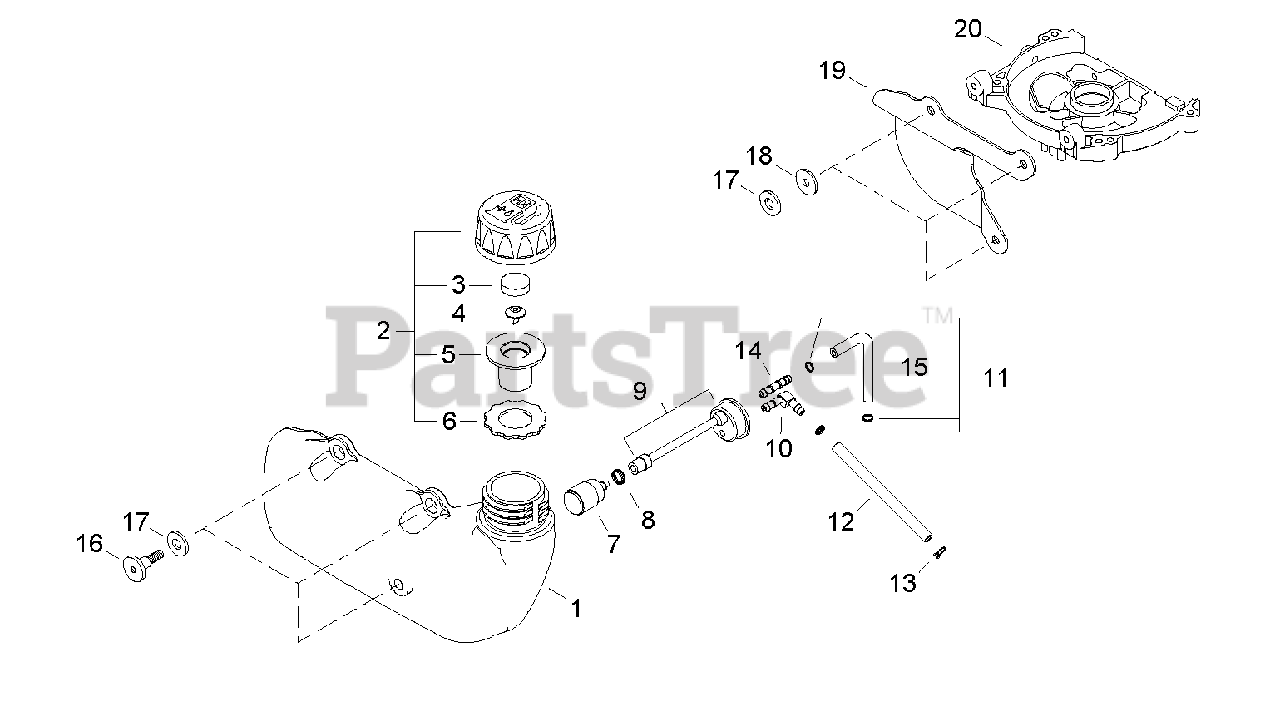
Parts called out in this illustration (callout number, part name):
1	TANK, FUEL
2	CAP ASSY
4	VENT, FUEL TANK
5	HOLDER, VENT
6	GASKET, CAP
7	FILTER, FUEL
8	CLIP - 7.8
9	FUEL PIPE ASSY
10	CONNECTOR, PIPE
11	CLIP - 6
12	PIPE - RETURN
13	CLIP - BUTTERFLY
14	CONNECTOR, PIPE
15	PIPE - FUEL
16	BOLT - 5
17	WASHER - 6
18	WASHER - 5
19	SHIELD, HEAT
20	CRANKCASE ASSY - FRONT
